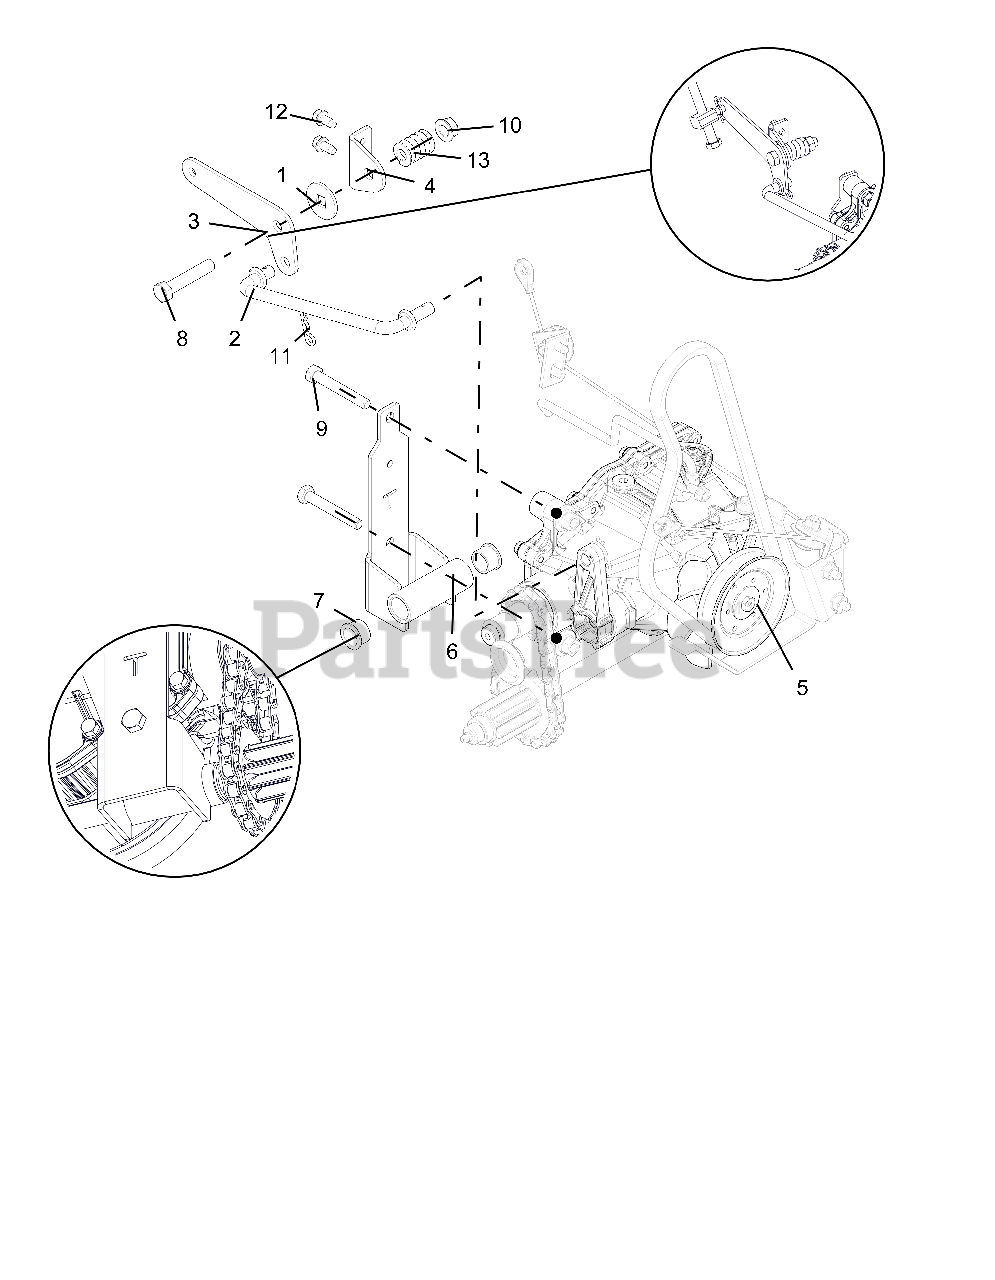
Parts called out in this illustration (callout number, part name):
1	FRICTION WASHER
2	ROD, HYDRO TRANS SHIFT
3	PIVOT, HYDRO TRANS SHIFT
4	BRACKET, HYDRO SHIFT PIVOT
5	TRANSMISSION, HYDROSTATIC
6	TRANS MOUNT, TENSIONING, TRACK
7	BSHG-FLG .625X.750X.500X.875
8	@BLT-HEX .38-16X2.00 GR5 YWZC
9	@BLT-HEX .31-18X2.25 GR5 YWZC
10	@NUT-LK-TOP-FLG .38-16 YWZC
11	PIN-HAIR INT .08X.18X1.18 YWZC
12	SCR-TAP .25-20X.50 HWH TR YWZ
13	SG-COMP .187X.56X1.62
